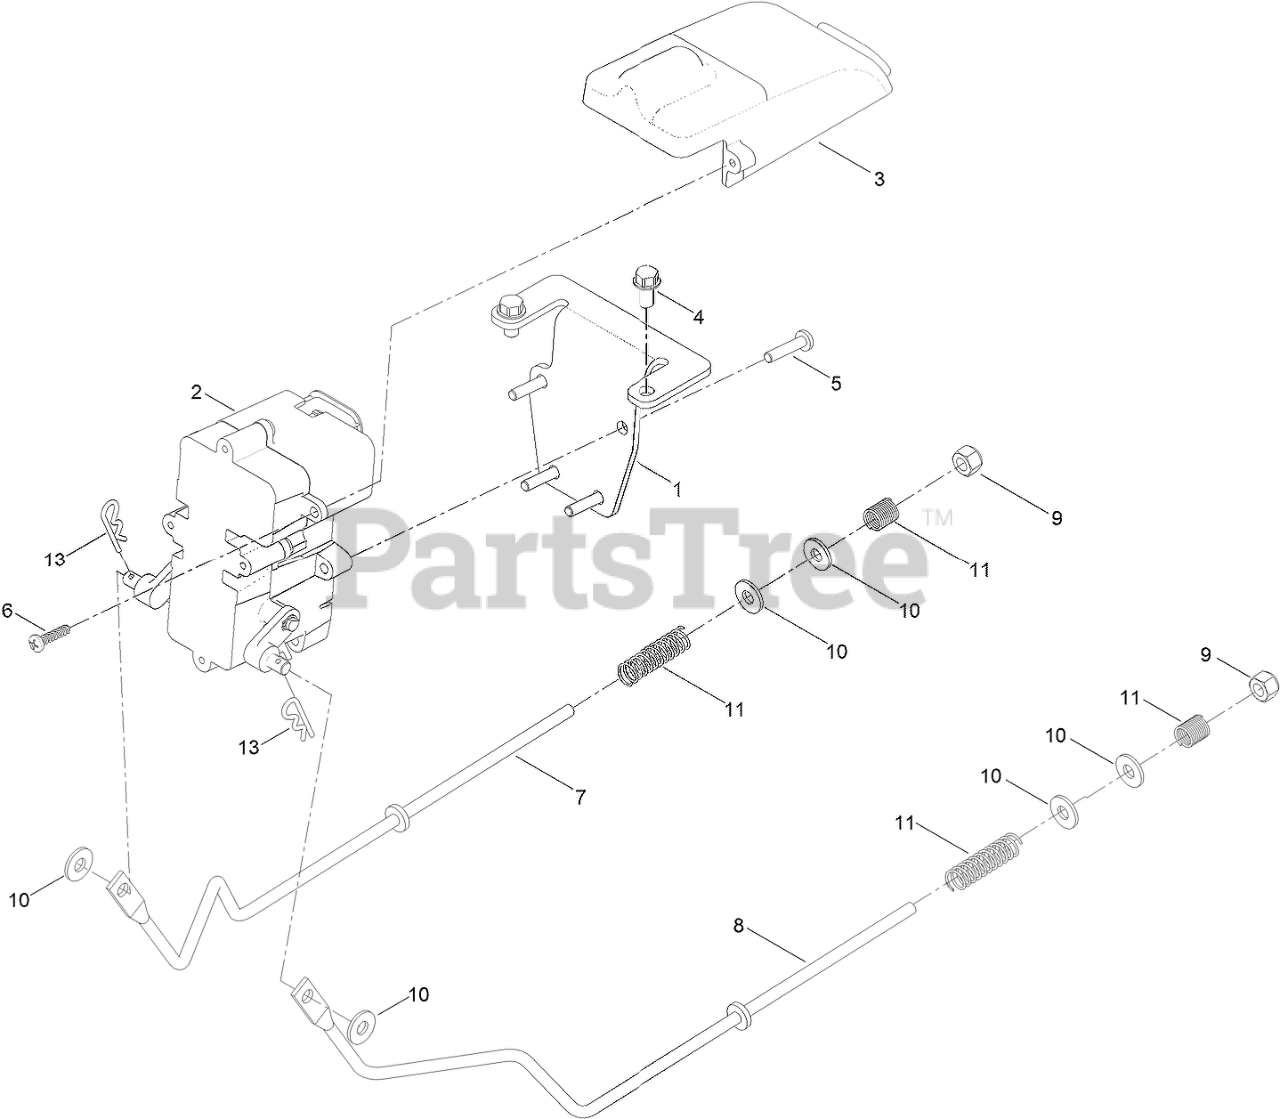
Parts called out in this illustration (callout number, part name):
1	BRACKET-MOUNT, BRAKE
2	BRAKE BOX ASM
3	COVER-CONNECTOR
4	SCREW-HWH
5	SCREW-PPH
6	SCREW-PPH
7	ROD-BRAKE, RH
8	ROD-BRAKE, LH
9	NUT-LOCK, NI
10	WASHER
11	SPRING-COMPRESSION
13	PIN-COTTER
